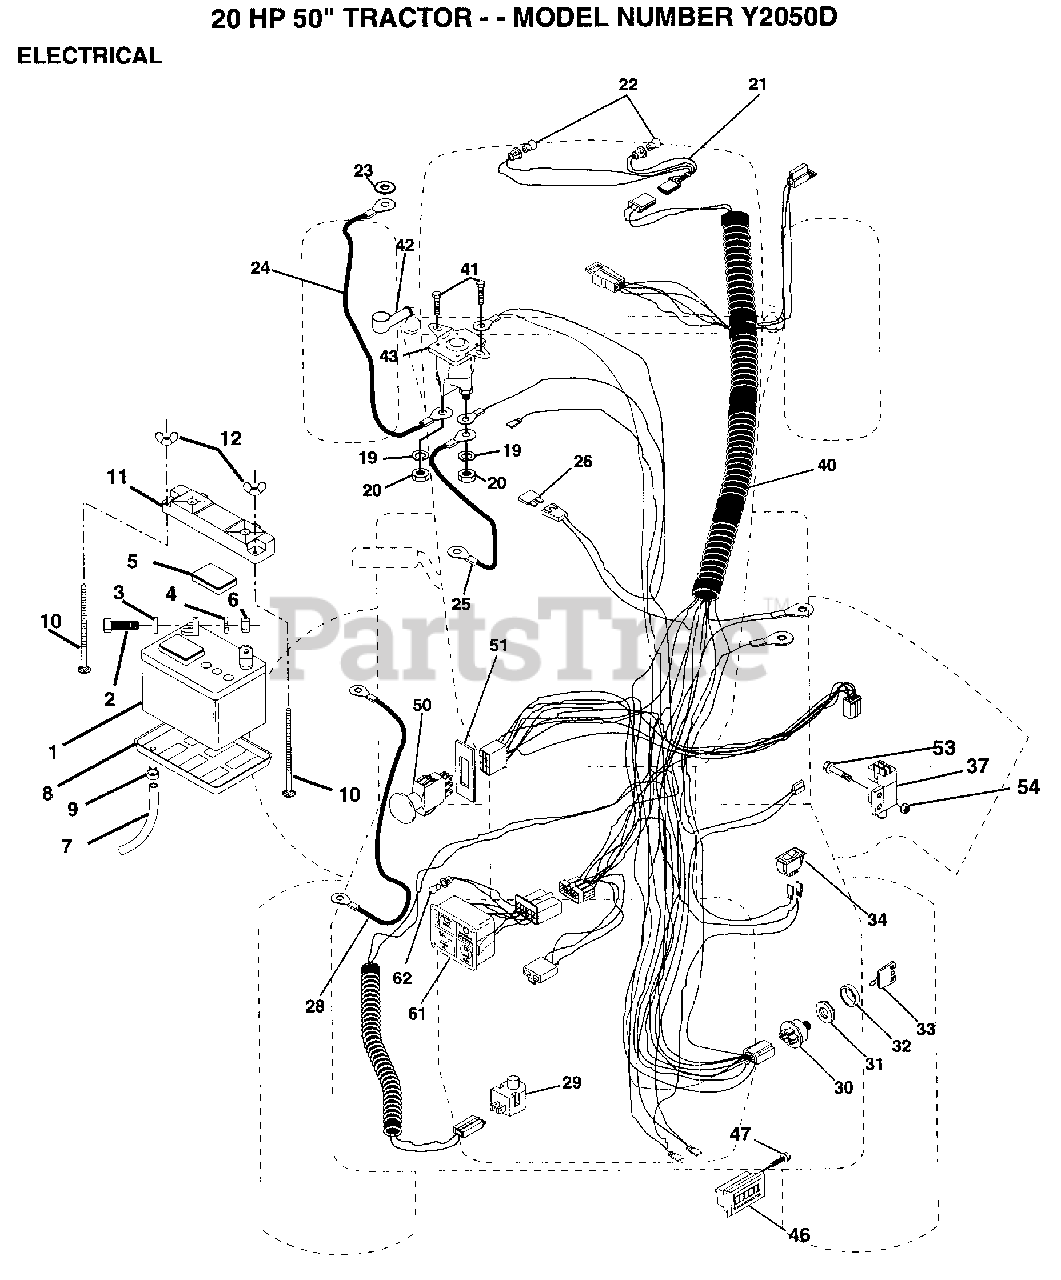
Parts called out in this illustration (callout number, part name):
2	BOLT LT
3	LOCKWASHER
4	WASHER
5	"CAP,BATTERY "
7	"DRAIN TU T, BATT"
8	"TRAY T, BATTERY"
9	HOSE CLAMP T
10	BOLT
20	NUT
22	HEADLAMP BULB
23	LOCKWASHER
24	"CABLE T, BATTERY"
25	CABLE-BATTERY T
26	FUSE HYT
28	CABLE T
29	SWITCH SEAT
32	COVER KEY SWITCH
33	KEY MLD GEN DELTA
34	SWITCH LT
37	SWITCH INTERLOCKT
40	HARNESS IGNITION
41	SCREW
46	HOUR METER T
47	SCREW
51	RING RETAIN PTO
53	SCREW
54	"NUT,KEPS"
61	LIGHT.PKG.ASM.
62	BULB LIGHT T
